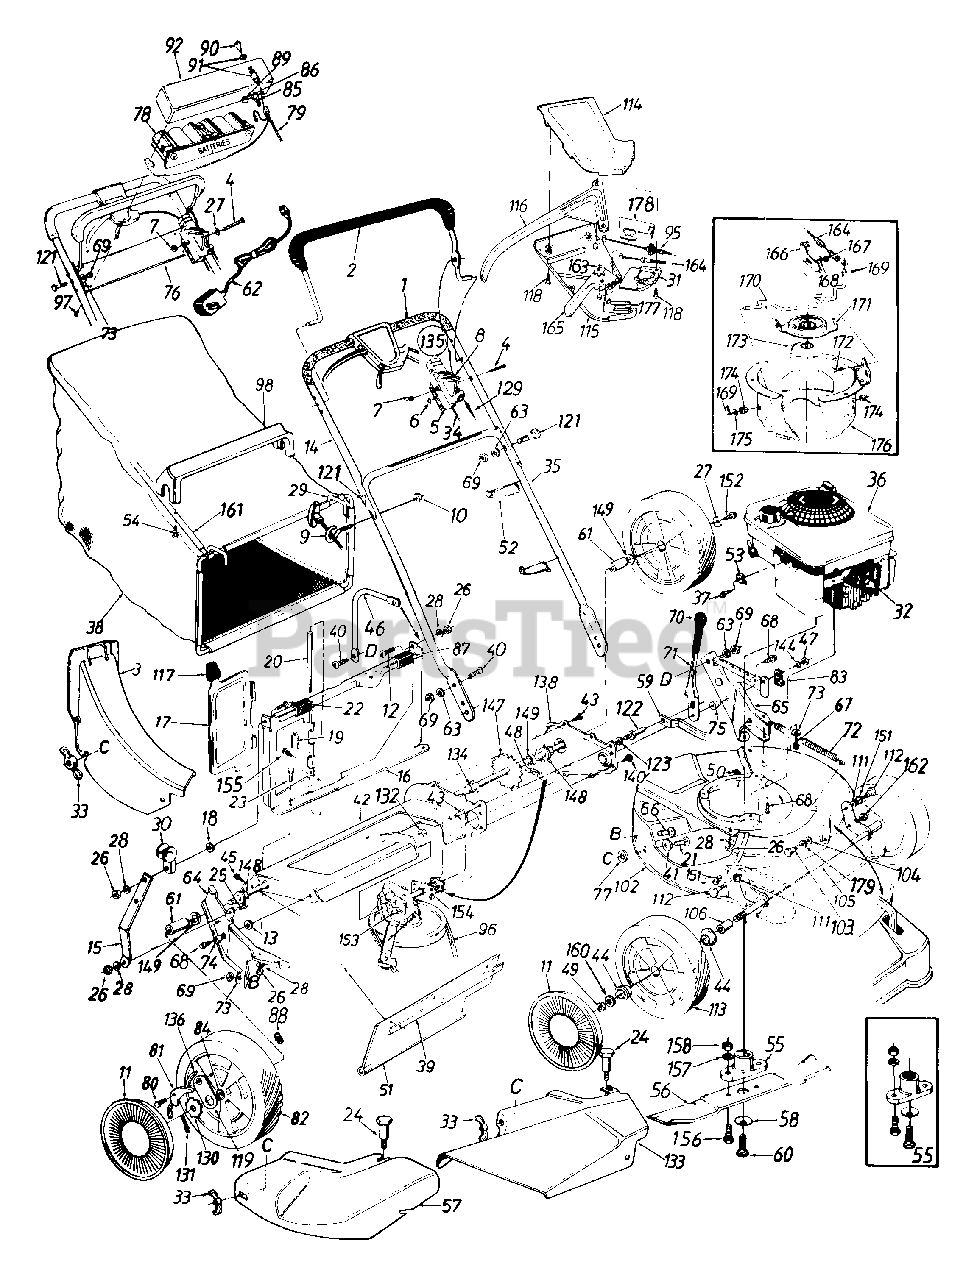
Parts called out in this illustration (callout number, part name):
1	Foam Grip
2	Control Handle Ass'y.
3	Rear Discharge Chute Ass'y.
4	Hex Bolt 1/4-20 x .2" Lg.
5	Throttle Body
6	Spr. Wash..66" I.D.
7	Hex L-Nut 1/4-20 Thd.
8	Throttle Lever
9	Rope Guide Bolt
10	Hex L-Nut 1/4-20 Thd.
11	Hub Cap
12	Truss Mach. Scr. 1/4-20 x .62" Lg.
13	Fl-Wash..383" I.D. x 1" O.D.
19	Torsion Spring
20	Pivot Pin
21	Carriage Bolt 1/4-20 x .62"
22	Truss Mach. Scr. 1/4-20 x 3/4" Lg.
23	Hex Bolt 1/4-20 x .50" Lg.
24	Shoulder Bolt .312 Dia. x .18 Lg.- Special
25	Hex Bolt 1/4-20 x .62" Lg.
26	Hex Nut 1/4-20 Thd.
27	Bell-Wash. 1/4" I.D.
28	L-Wash. 1/4" I.D.
30	Rope Guide
31	S.P. Control Cover
32	Spark Plug Insulator
33	Wing Nut w/Washer
34	Throttle Control Wire 61"
35	Lower Handle
37	Hex Self-Tap Scr. #10-32 x .62" Lg.
38	Grass Bag
39	Retaining Strip
40	Truss Mach. Scr. 5/16-18 x .75" Lg.
41	Fl-Wash..344" I.D. x .62"
44	Flange Ball Bearing 1/2" I.D.
45	Hex AB-Tap Scr. 1/4 x .62"
46	Catcher Panel Support Arm
47	Hex Patch L-Nut 3/8-24 Thd.
48	#48 Chain .500" Pitch x 30 Links
49	Hex Ins. Top L-Nut 3/8-16 Thd.
51	Rear Flap 3.75" x 17.30" Lg.
52	Cable Tie
53	Cable Clamp
54	Hex AB Scr. #12 x 1.25" Lg.
55	Blade Adapter Kit
56	21" Mulching Blade
57	Mulching Plug
58	Bell-Wash..46" I.D.
59	Height Adj. Connecting Arm
60	Hex Bolt 7/16-20 x 1.5" Lg. (Grade 5)
61	Spacer .513" I.D. x .703" O.D. x .69" Lg.
62	Battery Charger
63	L-Wash. 5/16" I.D.
64	R.H. Handle Wheel Brkt. Ass'y.
65	L.H. Handle Wheel Brkt. Ass'y.
66	Carriage Bolt 5/16-18 x .62"
67	Hex Wash. Hd. B-Tap Scr. 5/16-18
68	Hex Wash. Hd. TT-Tap Scr. 3/8-16
69	Hex Nut 5/16-18 Thd.
71	Height Adj. Lever
72	Extension Spring .75" O.D. x 8" Lg.
73	Bell-Wash. 5/16" I.D.
74	Spacer
75	Shld. Spacer .500" Dia.
78	12 Volt Battery
79	Wire Harness
80	Shld. Scr..342" Dia. x .268
81	Pawl
82	Rear Wheel Ass'y. Comp.
83	Clamp
84	Bearing 112" I.D.
85	Plug
86	Fuse Holder
87	Panel Clip
88	Weld L-Nut 1/4-20 Thd.
89	Fuse 7-1/2 Amp.
90	Key
91	Key Switch
92	Upper Battery Tray
95	S.P. Cable
96	"V"-Belt
97	Hex AB-Tap Scr. 1" Lg.
98	Bag Handle
102	21" Deck Ass'y.
103	Shld. Bolt .5" Dia. x .295
104	Bell-Wash..515" I.D. x 1.0" O.D.
105	Front Axle Ass'y.
106	Sleeve .526" I.D. x .690" O.D. x .880" Lg
111	Intern. L-Wash. 3/8 I.D.
112	Shld. Bolt .575" Dia. x .42
113	Front Wheel Ass'y. Comp.
114	Self-Propelled Control Cover
115	Self-Propelled Control Cover
116	Control Lever
117	Door Grip
118	Fl-"C"-Sunk Hd. Tap Scr. #10 x .75" Lg.
119	Pawl Plate
121	Curved Carr. Bolt 5/16-18 x 1.38" Lg.
122	Shld. Pin 3/8-24 x 1.43" Lg.
123	L-Wash. 3/8" I.D.
129	Control Cable 47" Lg.
130	Ratchet Wheel 1.62" O.D.
131	Cotter Pin 1/8" Dia. x 1.00" Lg.
132	Hex Jam Nut 3/8" I.D.
133	Side Chute Deflector Ass'y.
134	Hex Flange Bearing
135	Throttle Box Comp.
136	Spring-Nylon
144	Fl-Wash..385" I.D. x 87"
147	Rear Shaft Ass'y. 21.94" Lg.
148	Hex Flange Bearing .506" I.D. Plastic
149	Fl-Wash..531" I.D. x .930"
151	Flanged Nyliner Brg.
152	Hex Bolt 1/4-20 x .62" Lg. (Grade 5)
153	Transmission Comp. (See Breakdown)
154	Hex Bearing Cup
155	Hex B-Tap Scr #10 x 38
156	Hex Scr. 3/8-24 x 1.0" Lg.
157	L-Wash. 3/8" I.D.
158	Hex Nut 3/8-24 Thd.
160	Fl-Wash..385" I.D. x .87" O.D.
162	Hex Jam Nut 3/8-16 Thd.
163	3 Tooth Rack Gear Insert
164	Spd. Control Cable - 50" Lg.
165	6-Spd. Shift Lever
168	Hex Cent. L-Nut 1/4-20 Thd.
169	Cot-Pin 3/32" Dia. x .75" Lg.
170	Shift Rod
171	Movable Pulley Half Ass'y.
172	Carr. Bolt 1/4-20 x .50" Lg.
173	Splined Pulley Half
174	Flanged Bushing
175	Fl-Wash..328" I.D. x .68" O.D.
176	Cable Mtg. Brkt. Ass'y.
177	Shift Lever Spring
178	6-Speed Rack Cable Brkt.
179	Fl-Wash. .51" I.D. x .75"
